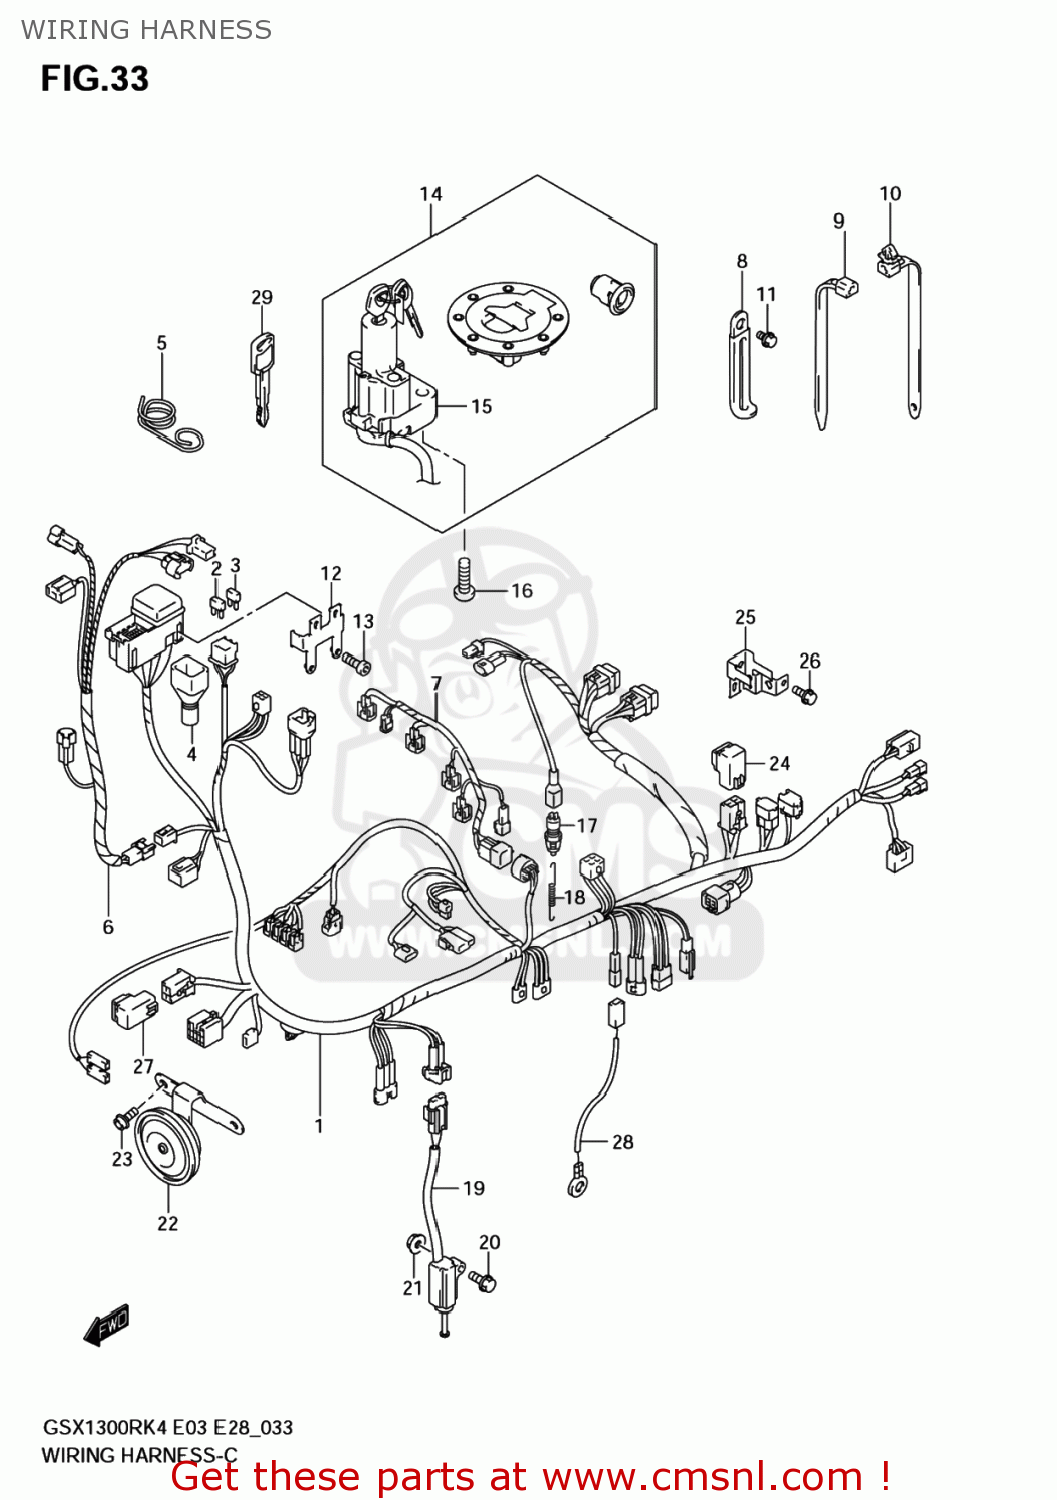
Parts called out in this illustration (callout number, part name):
1	HARNESS,WIRING
2	FUSE(10A)
3	FUSE(15A)
4	COVER,SPEEDOMETER COUPLER
5	GUIDE,WIRING HARNESS
6	HARNESS,WIRING NO.2
7	WIRE,INJECTOR LEAD
8	CLAMP(L:45)
9	CLAMP(L:125)
10	CLAMP(L:90)
11	BOLT
12	BRACKET,FUSE BOX
13	BOLT
14	LOCK SET
15	LOCK ASSY,STEERING
16	BOLT(8X20)
17	SWITCH ASSY,STOP LAMP
18	SPRING
19	SWITCH ASSY,SIDE STAND
20	BOLT(8X35)
21	NUT
22	HORN ASSY
23	BOLT
24	RELAY ASSY
25	BRACKET,FUEL PUMP RLY
26	BOLT
27	RELAY ASSY
28	WIRE,OIL PRESSURE SWITCH LEAD
29	KEY,BLANK
